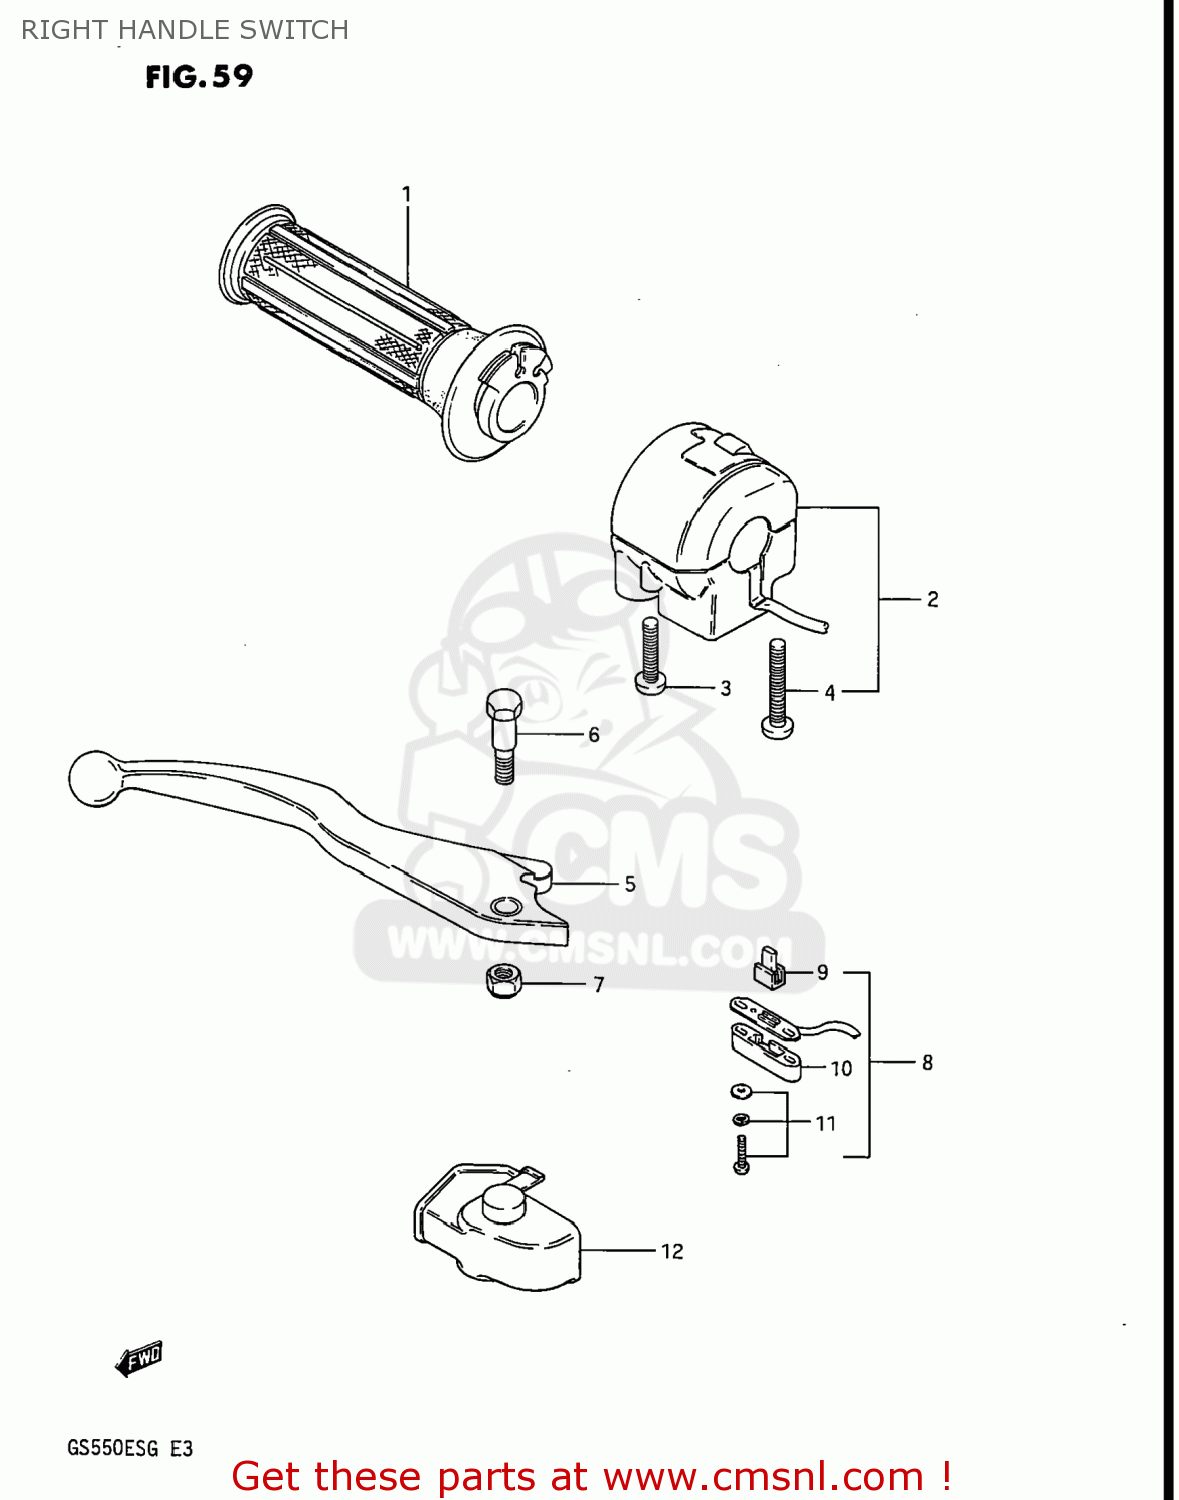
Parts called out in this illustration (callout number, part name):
1	GRIP,THROTTLE
2	SWITCH ASSEMBLY,HANDLE,RIGHT
3	SCREW
4	SCREW
5	LEVER,BRAKE
6	BOLT,LEVER PIVOT
7	NUT
8	SWITCH ASSEMBLY
9	CONTACT,SWITCH
10	COVER,FR BK TERMINAL BASE
11	SCREW
12	COVER,BRAKE LEVER
